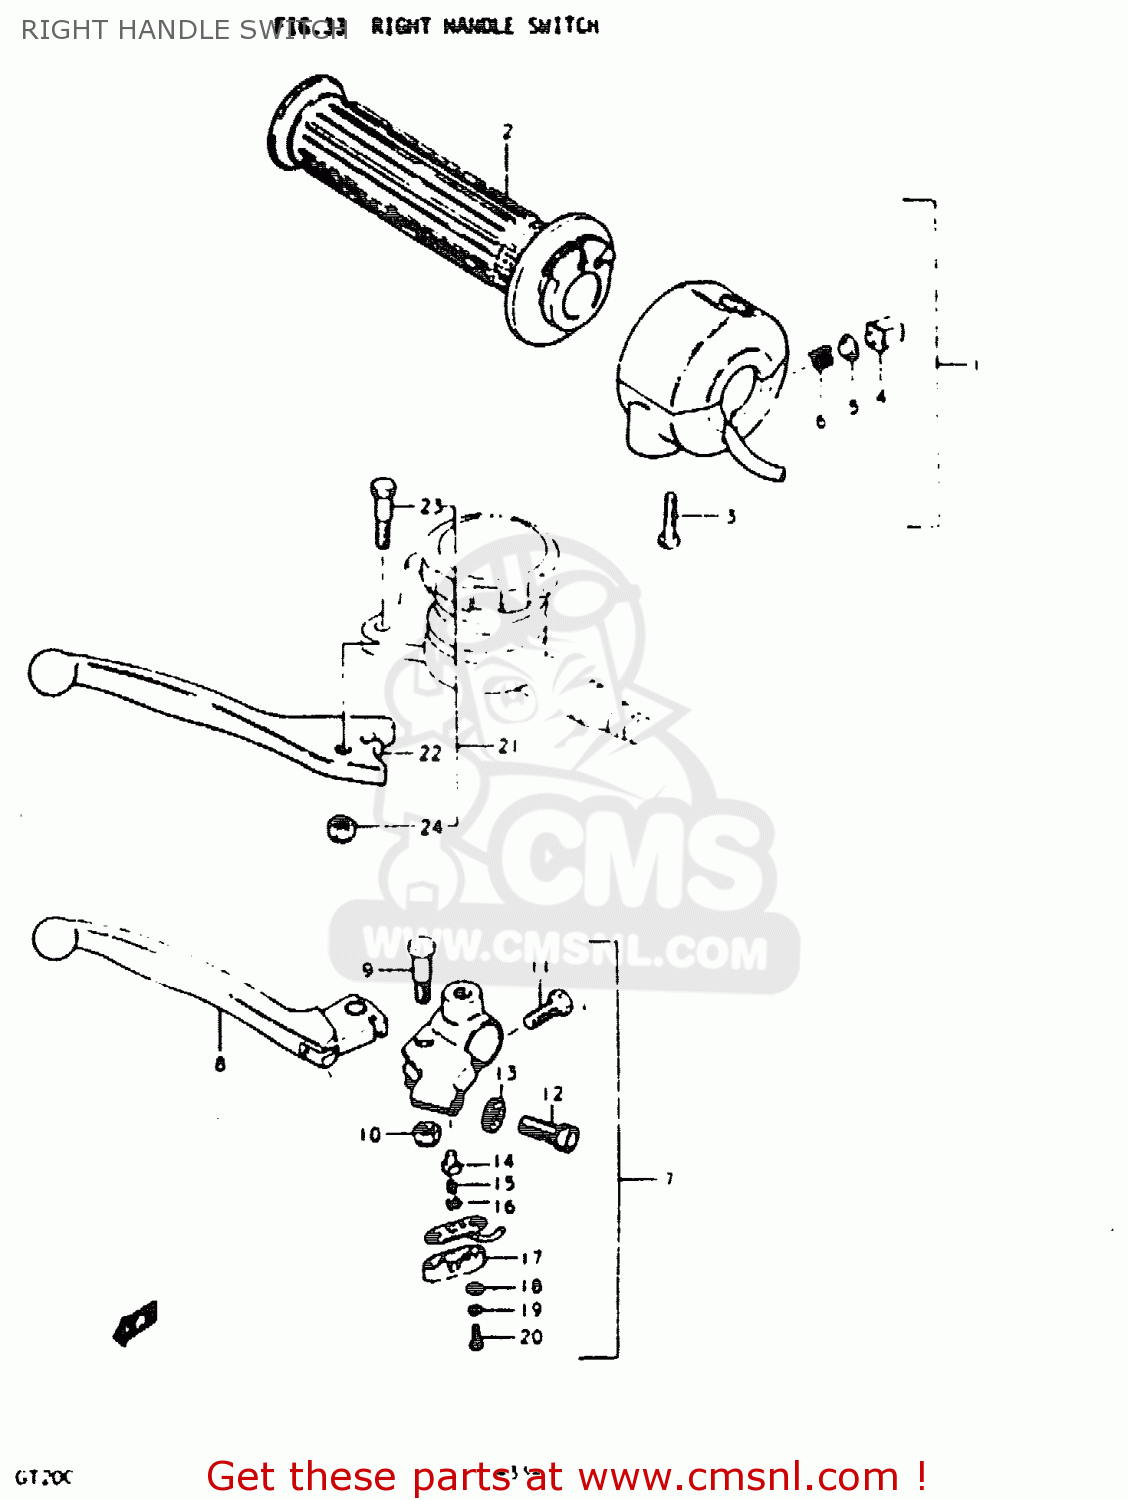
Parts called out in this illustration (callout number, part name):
1	GRIP ASSY, THROTTLE
2	GRIP,THROTTLE
3	SCREW
4	BUTTON,HORN
5	CONTACT
6	SPRING
7	BRAKE LEVER & SWITCH ASSY
8	LEVER,BRAKE
9	BOLT,LEVER
10	NUT 6MM
11	BOLT
12	ADJUSTER,CABLE
13	NUT,CABLE ADJUSTER
14	HOLDER
15	SPRING
16	PLATE
17	COVER,FR BK TERMINAL BASE
18	WASHER
19	LOCK WASHER
20	SCREW
